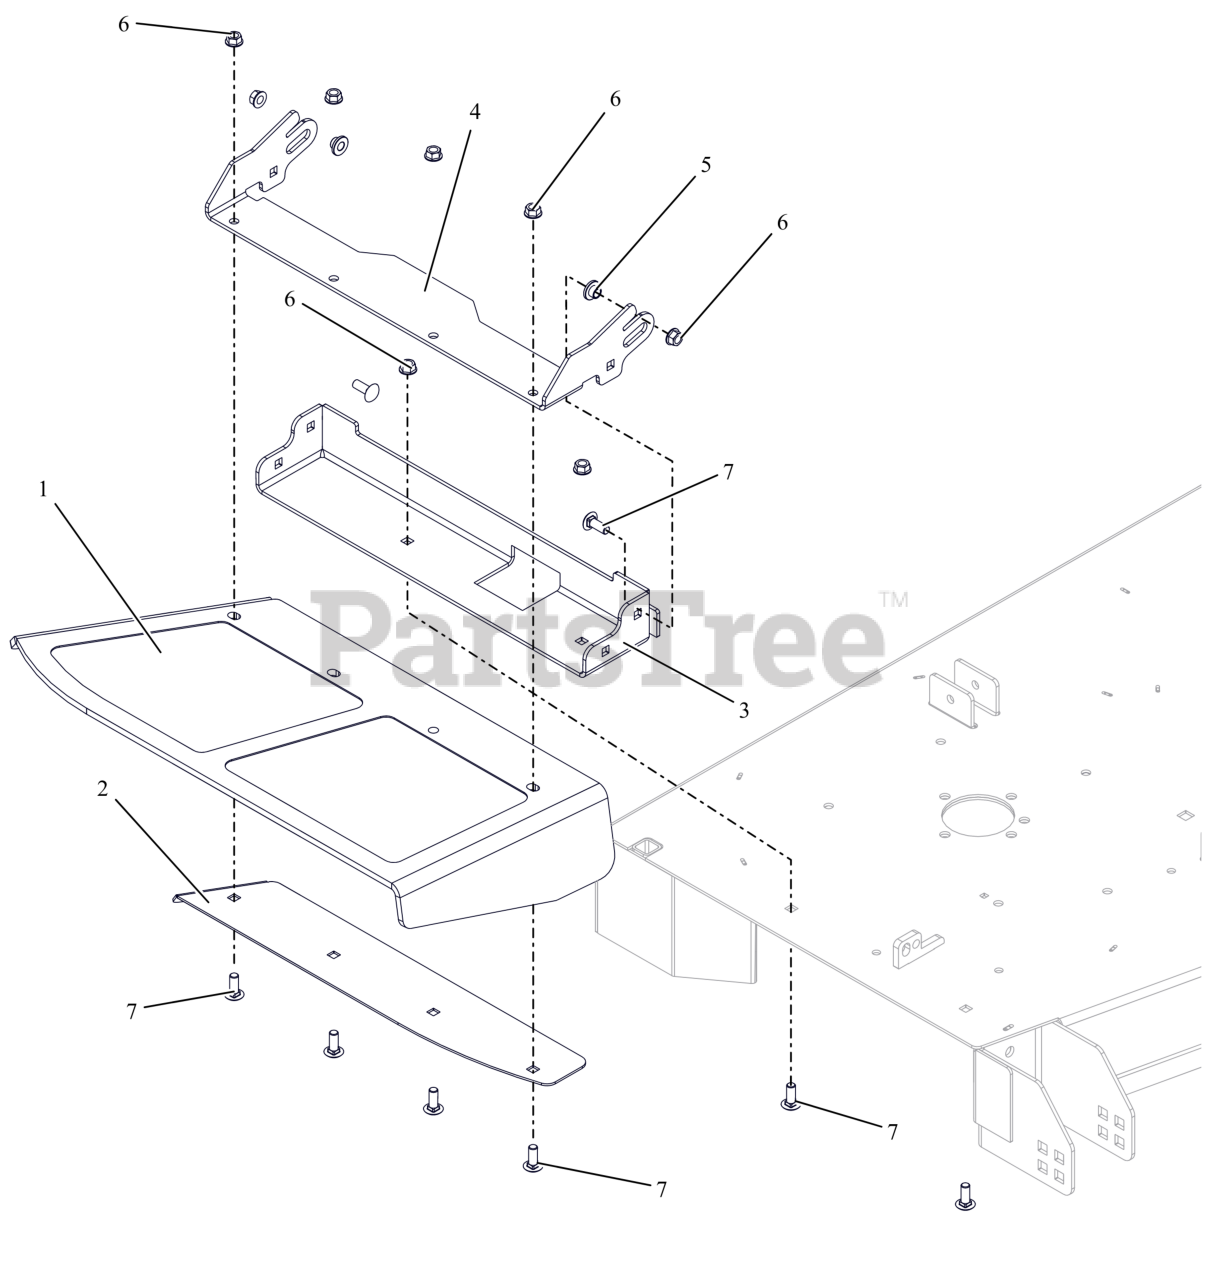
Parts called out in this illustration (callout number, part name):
1	CHUTE, FORMED RUBBER DISCHARGE
2	PLATE, DISCH CHUTE CLAMP (BLACK)
3	KIT,DISCH CHUTE LG BLK W/DECAL
4	BRKT- CHUTE MTG
5	BSHG-FLG .385X.500X.875X.406
6	NUT-LK-CTR-FLG .375-16 GF ZCC
7	BLT,RHSSN .38-16X1.00 G5 ZCC
